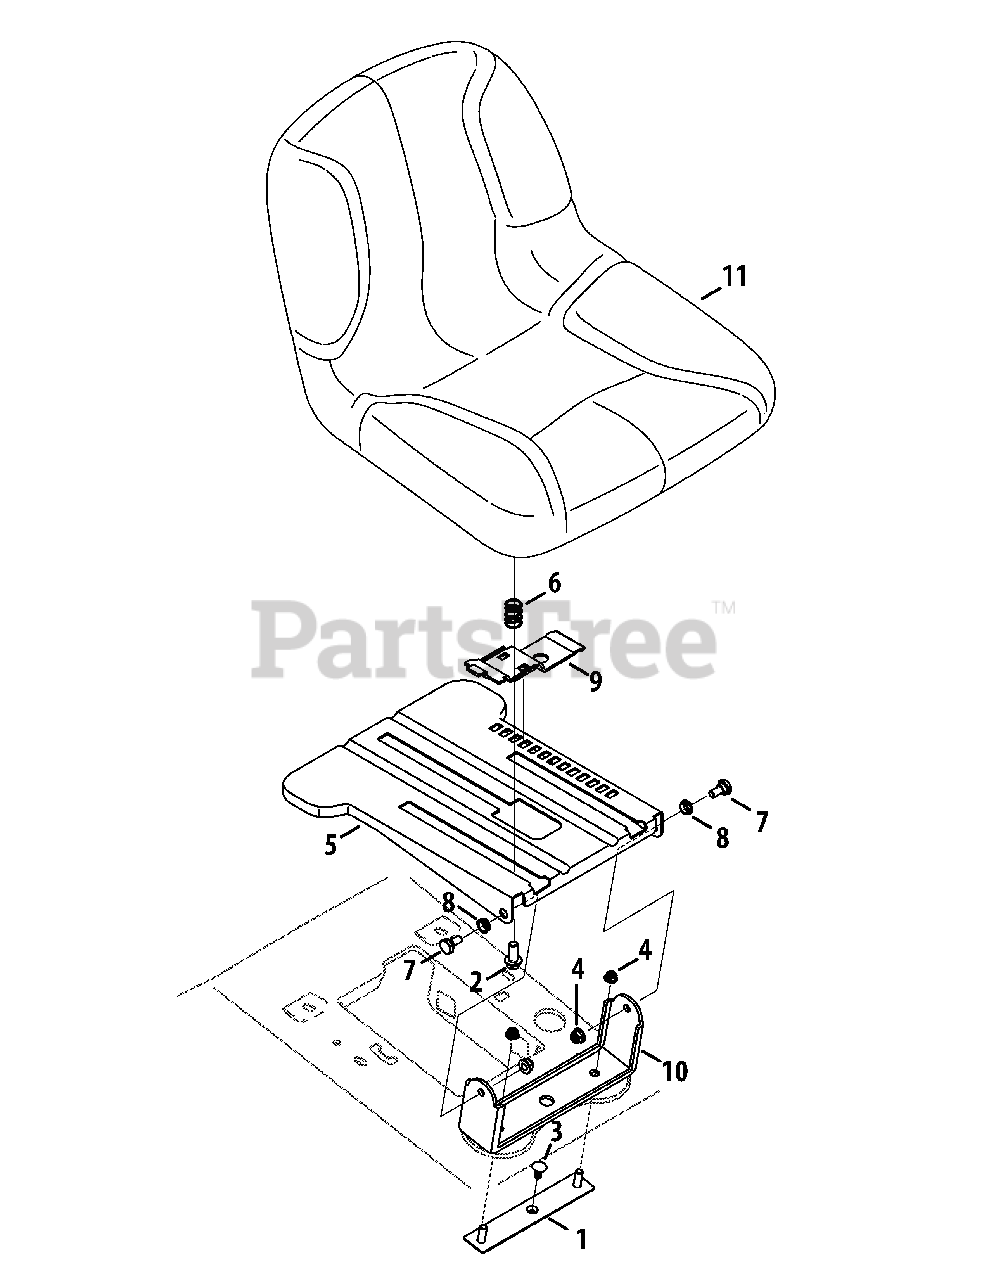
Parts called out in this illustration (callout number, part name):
1	Seat Pivot Plate Assembly
2	Hex Flange Screw, 3/8/16, .875, Gr5
3	Ratchet Clip
4	Nut, Flange Lock, 5/16-18, Grf
5	Bracket, Mounting, Seat
6	Compression Spring, .68 x 1.065 x .055
7	Shoulder Screw, .435 x .178, 5/16 x .56
8	Flange Bearing, .4385 ID
9	Seat Lever
10	Pivot Bracket, Tall
11	Seat, High
